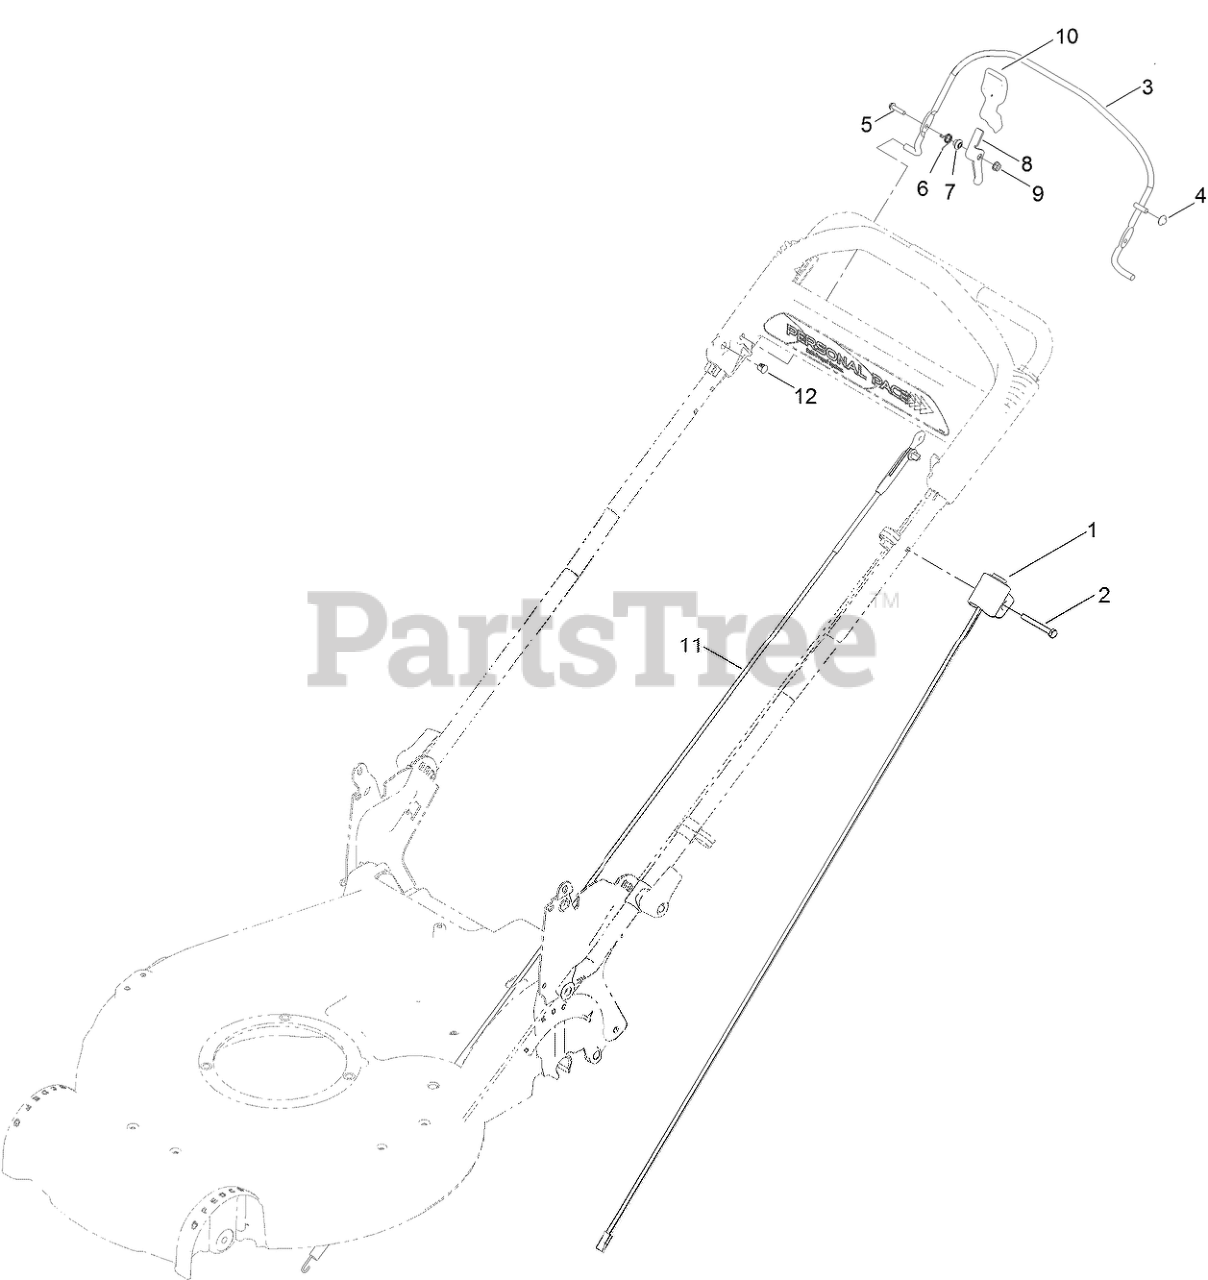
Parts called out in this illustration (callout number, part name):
1	HARNESS
2	SCREW-HH
3	BAIL-BRAKE
4	NUT-SPEED
5	SCREW-HWH
6	SPRING-TORSION
7	SPACER
9	NUT-LOCK, FLANGE
11	CABLE ASM
12	PLUG-DOME
